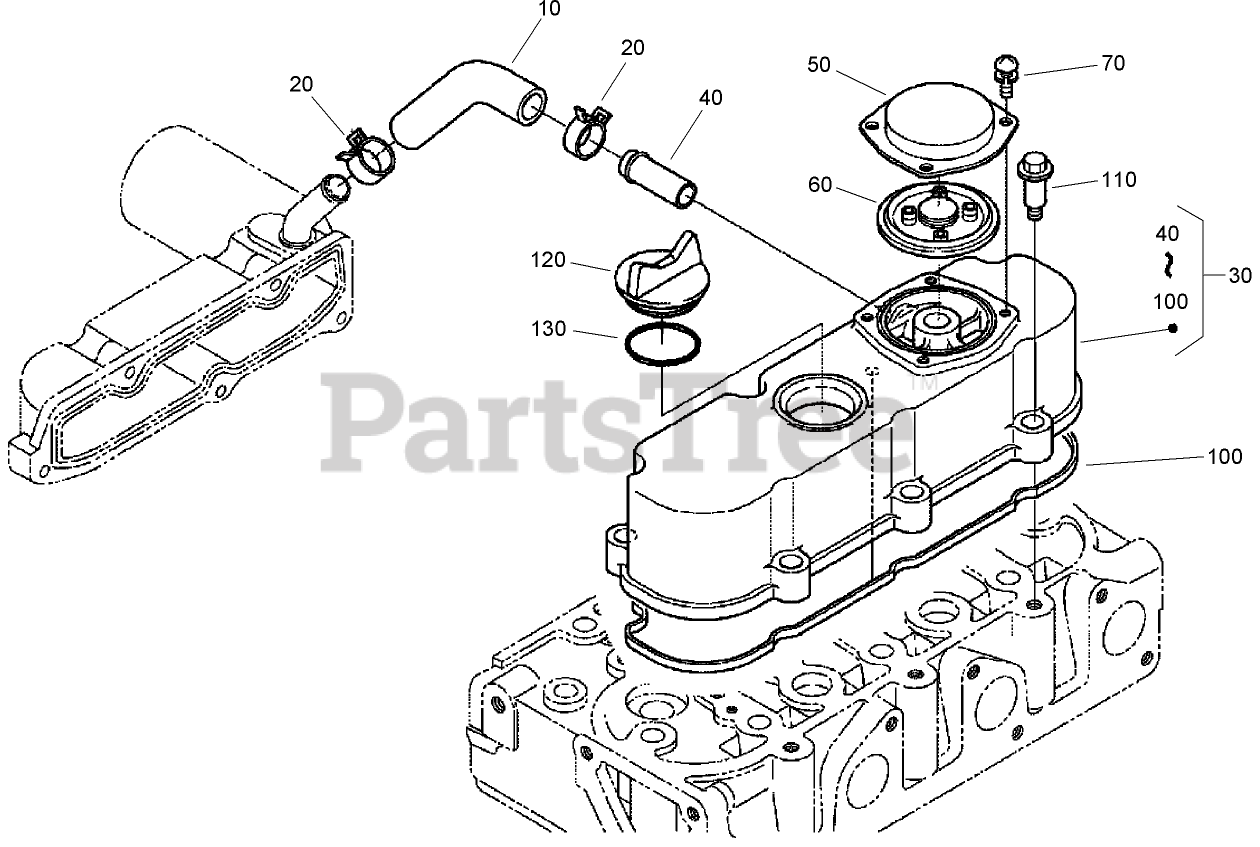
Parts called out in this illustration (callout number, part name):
10	TUBE-BREATHER
20	CLAMP-HOSE
30	CYLINDER HEAD COVER ASM
40	PIPE-RETURN, WATER
50	COVER-BREATHER
60	VALVE-BREATHER
70	SCREW (WITH WASHER)
100	GASKET-COVER, HEAD
120	PLUG-FILLER, OIL
130	O-RING
